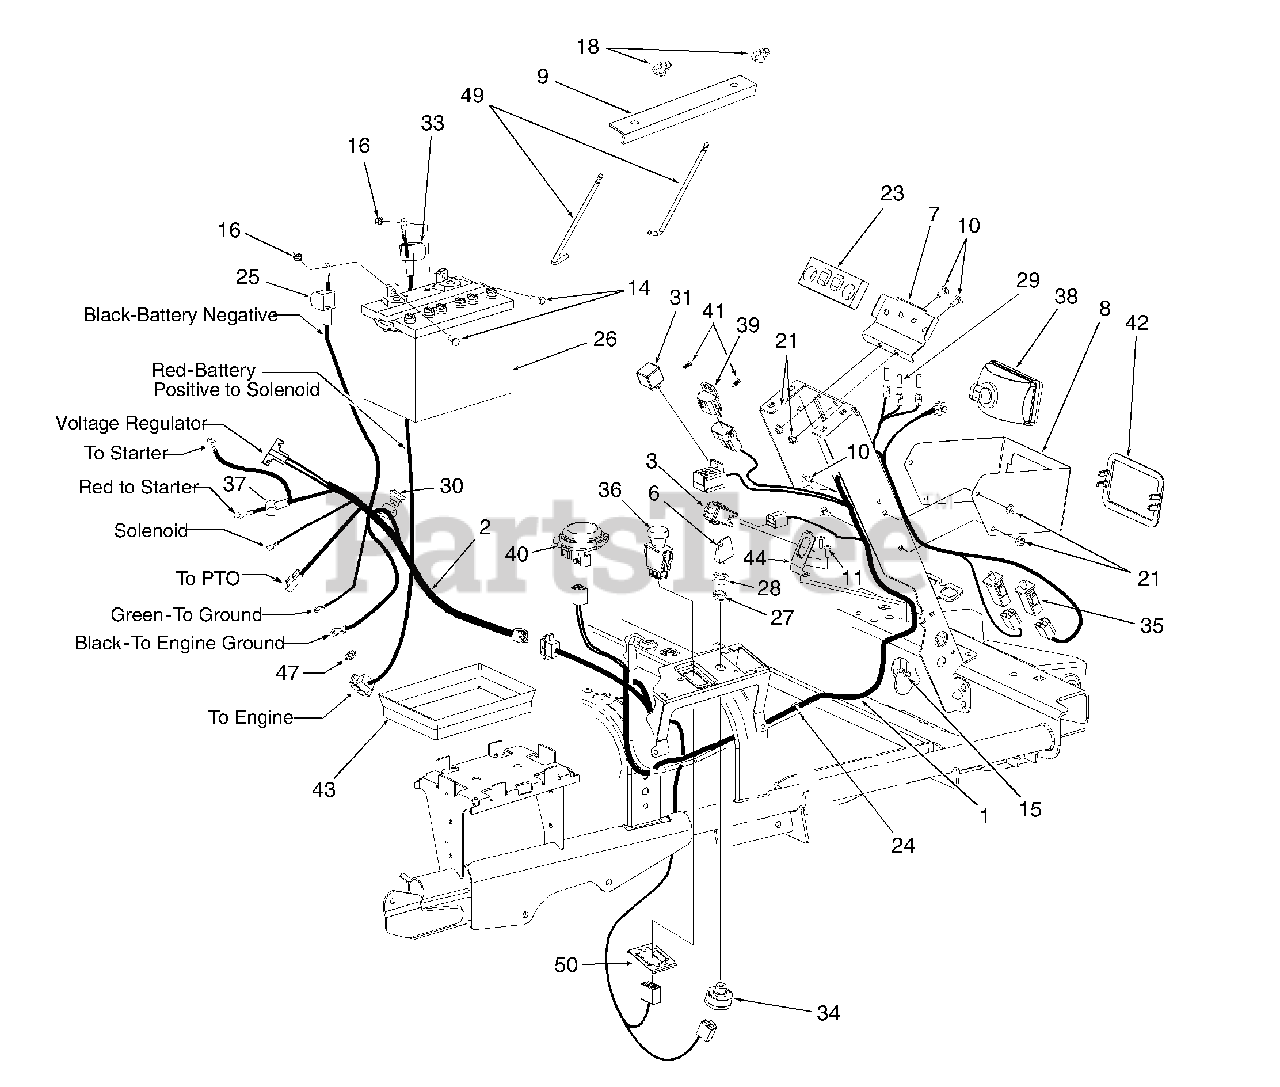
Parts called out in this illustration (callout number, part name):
1	Wire Harness, Main
2	Wire Harness, Engine
3	Switch, Plunger Safety
6	Key, Ignition
10	Bolt, Carriage, 1/4-20 x .62
11	Screw, Machine, #10-24 x 5/8
14	Screw, Hex Cap, 1/4-20 x .75 GR5
15	Nut, Hex Insert Lock, #10-24
16	Nut, Hex Sems, 1/4-20
18	Nut, Nylon Wing, 1/4-20
21	Nut, Hex Flange Lock, 1/4-20
23	Foam Protector, Indicator Light
25	Cover, Battery Terminal - Black
26	Battery
27	Nut, Ignition Switch, 5/8-32
28	Cap, Ignition Switch
29	Bulb, Indicator
30	Fuse, Mini, 20 Amp
31	Relay
33	Cover, Battery Terminal - Red
34	Switch, Ignition
35	Switch, Plunger Safety
36	Switch, PTO
37	Cover, Terminal - Red
38	Headlight Assembly
39	Sensor, Voltage
40	Switch, Seat
41	Retainer, Ratchet
42	Bezel, Headlight
43	Tray, Battery
44	Spring, Switch Mounting
49	Rod, Battery Retainer
50	Bracket, PTO Switch Retainer
